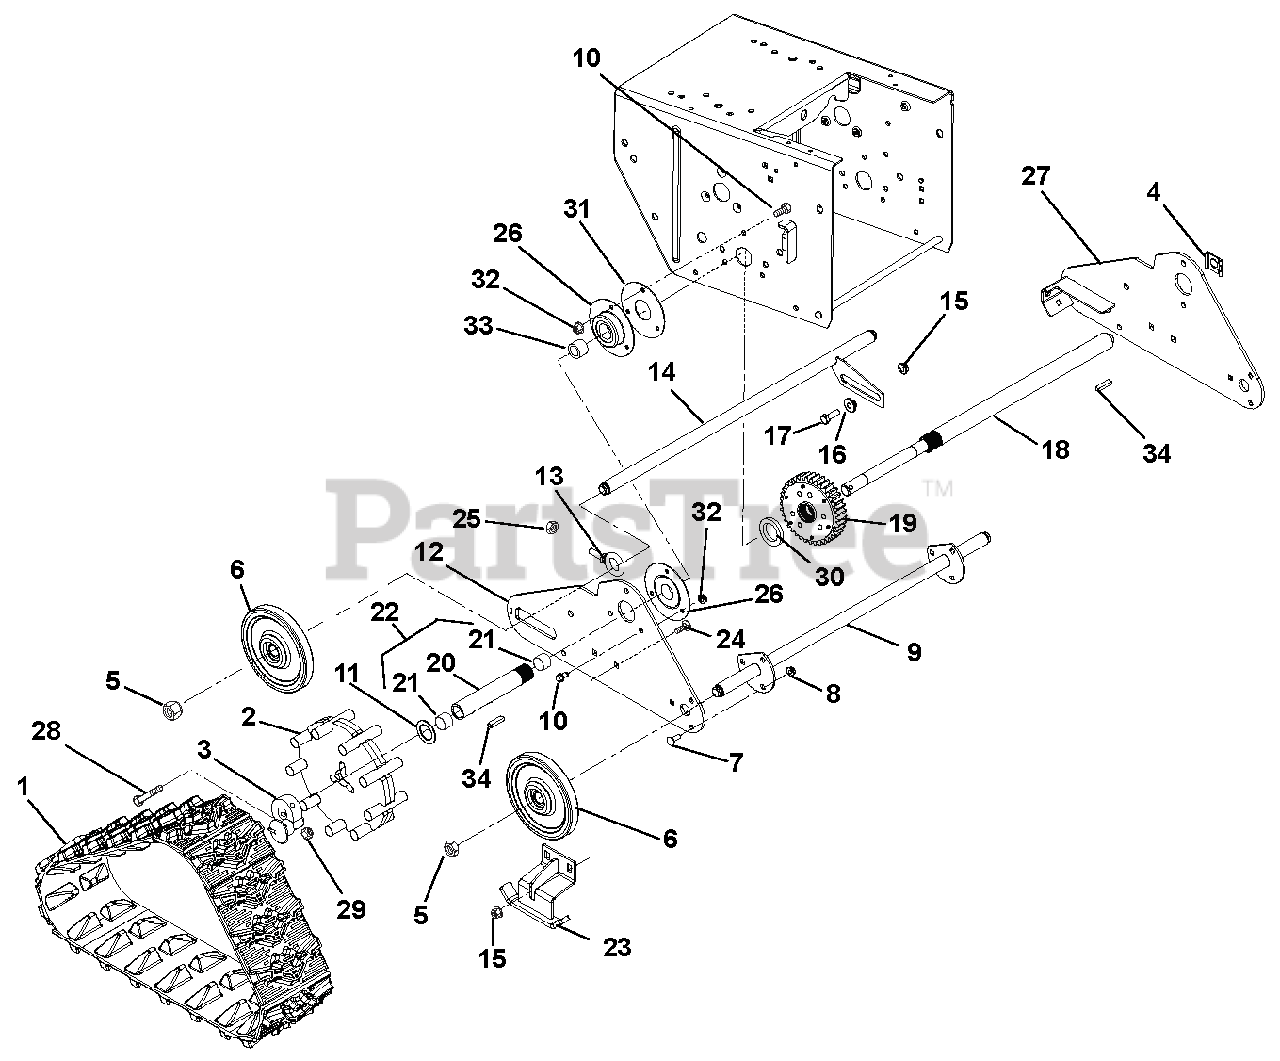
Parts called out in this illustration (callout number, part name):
1	TRACK, RUBBER
2	WHEEL, DRIVE-TRACK
3	HUB, LOCKOUT-ASSEMBLY
4	CLIP, SNAP .625 DIA
5	@NUT-LK-NYL .625-18 YWZC
6	WHEEL, BOGIE - SINGLE BEARING
7	@BLT-RDHDSQNK .25-20X.75 G5YZ
8	@NUT-LK-TOP-FLG .25-20 YWZC
9	AXLE, FRONT - PRO
10	@BLT-HEX .25-20X.75 GR5 YWZC
11	WSHR-FL-STL 1.010X1.505X.062YZ
12	SIDE PLATE, RH-TRACK
13	BLT-EYE .375-16X.880 YWZC
14	AXLE, REAR - PRO TRACK
15	@NUT-LK-TOP-FLG .31-18 YWZC
16	BSHG-FLG .325X.499X.3X.875
17	@BLT-HEX .31-18X1.00 GR5 YWZC
18	AXLE, LONG-TRACK DIFFERENTIAL
19	DIFFERENTIAL, AXLE LOCK
20	AXLE, SHORT-TRACK DIFFERENTIAL
21	BSHG-SLV .706X.764X.75 BRZ
22	AXLE, SHORT-TRACK W/BUSHINGS
23	RUNNER, GUIDE-TRACK
24	@BLT-RDHDSQNK .31-18X.75 G5YZ
25	NUT-LK-CTR-FLG .38-16 YWZC
26	BRG-FLG 1.003/1.000 3 BOLT
27	SIDE PLATE, LH-TRACK
28	@BLT-HEX .25-20X2.00 GR5 YWZC
29	@NUT-LK-CTR .25-20 YWZC
30	WSHR-FL-NY 1.38X2.00X.25
31	PLATE, BEARING SPACER
32	@NUT-LK-TOP-FLG .25-20 YWZC
33	BSHG-SLV, 1.012X1.125X1.00
34	KEY-RECT .25X.188X1.00
